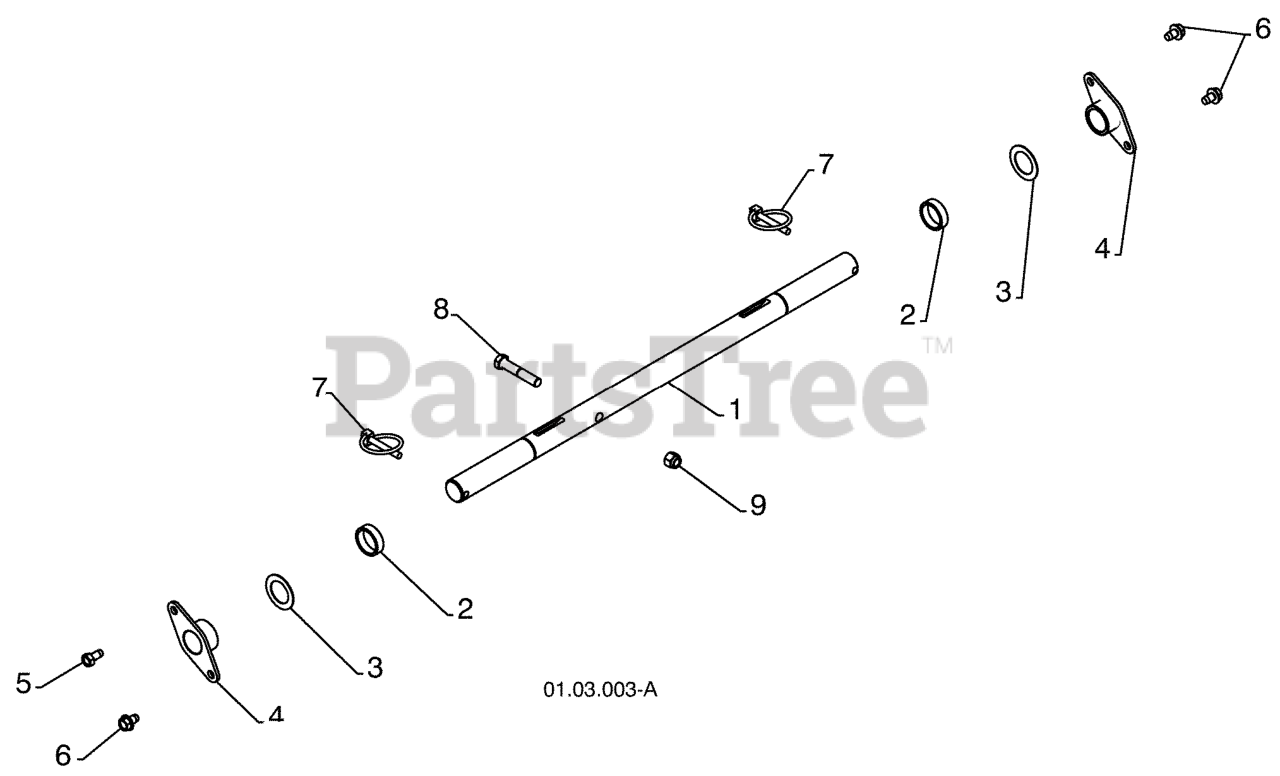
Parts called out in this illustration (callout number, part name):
1	SHAFT.AXLE.POWER.STEERING.HYD
2	SPACER.AXLE.RH
3	WASHER TRUST 1"
4	BEARING, AXLE
6	BOLT 5/16--18 X .500
7	PIN KLIK, 1/4
8	CAP.SCREW.HEX.HD.3/8-16
9	NUT
